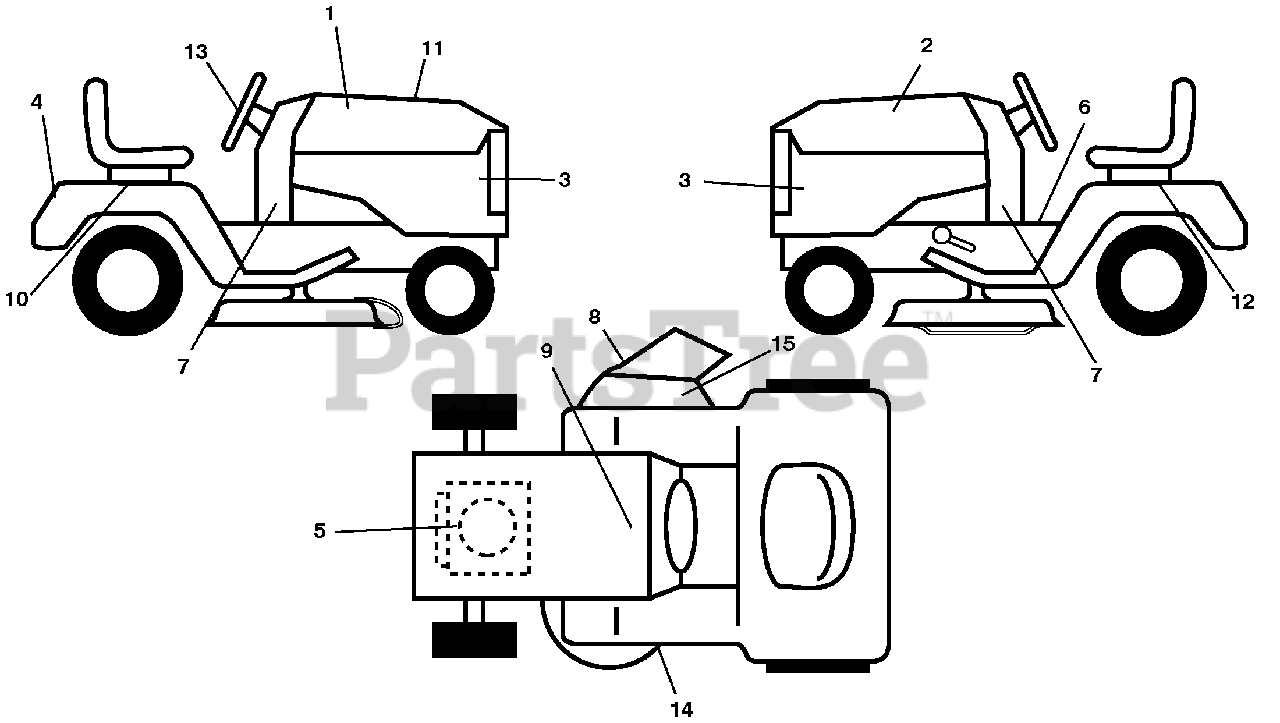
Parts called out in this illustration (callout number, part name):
1	Decal, Hood RH
2	Decal, Hood LH
3	Decal, Side Panel
4	Decal, Fender
5	Decal, Engine
6	Decal, Fender Operator's
7	Decal, Lower Dash
8	Decal, Warning
9	Decal, Battery Danger/Poison
10	Decal, Fender RH
11	Decal, Replacement
12	Decal Fender LH
13	Decal, Steering Wheel
14	Decal, Mower Schematic
15	Decal, Caution
15	Decal, Bypass
15	Pad, Foot Pedal Control
15	Pad, Footrest, LH
15	Manual, Operator's (Eng/French)
15	Manual, Parts
